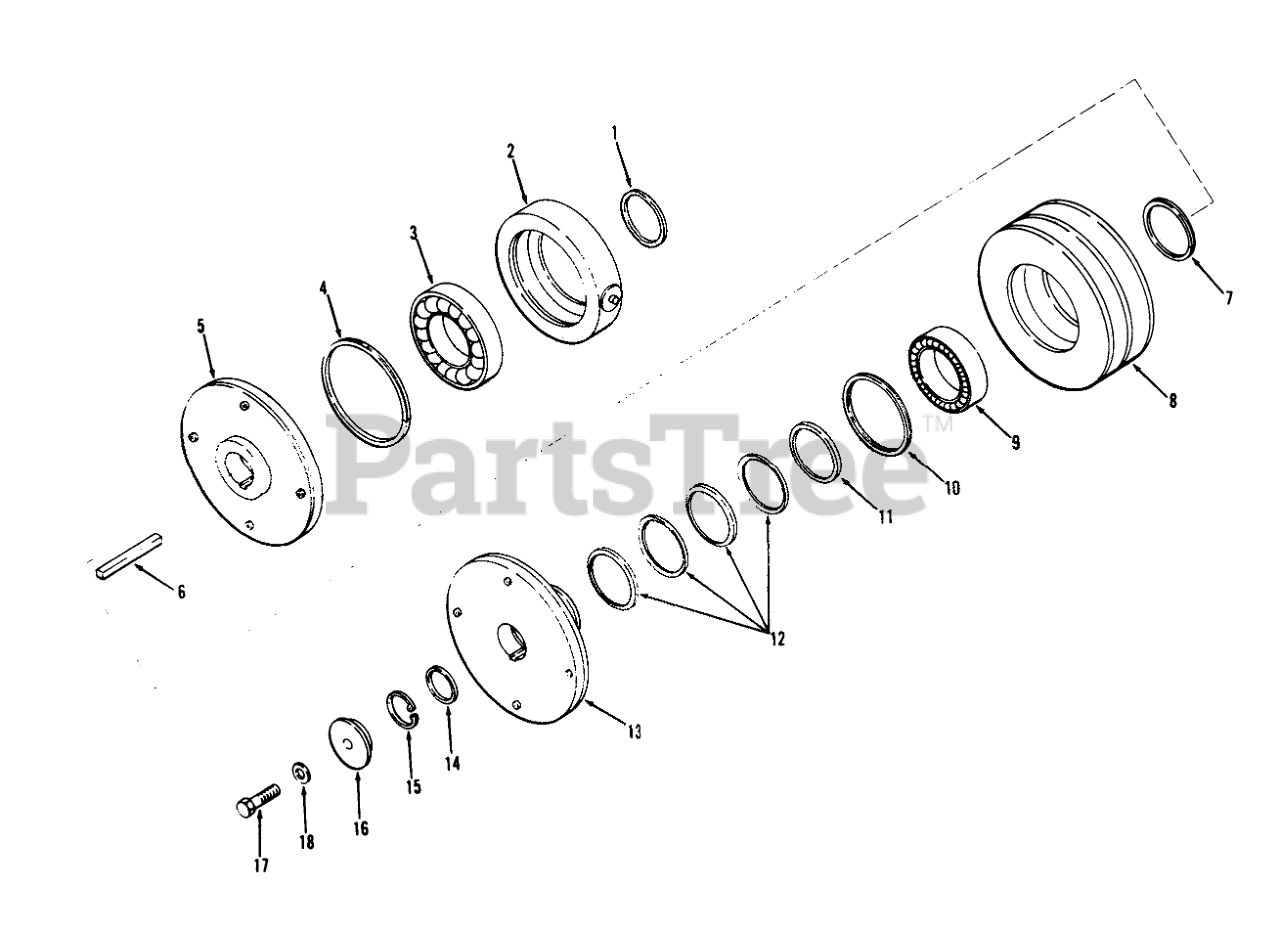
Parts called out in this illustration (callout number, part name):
1	Rotor Assembly
1	RING EXTERNAL
2	Field Assembly
2	ASSY COLLAR
3	Screw
3	BEARING
4	Lockwasher Internal
4	RING INTERNAL
5	Sleeve
5	ASSY CLUTCH PLATE
6	BOLT
7	Washer .406 x 1.75 x .187
7	RING EXTERNAL
8	LOCKWASHER
8	PULLEY CLUTCH
9	Assy-Wire and Plug
9	BEARING
10	Bolt
10	RING INTERNAL
11	Nut
11	WASHER
12	Washer-Copper
12	SPRING WASHER
13	Assy-Outer Clutch
14	NUT
14	WASHER
15	Spring
15	INTERNAL RING
16	END CAP
18	LOCKWASHER
